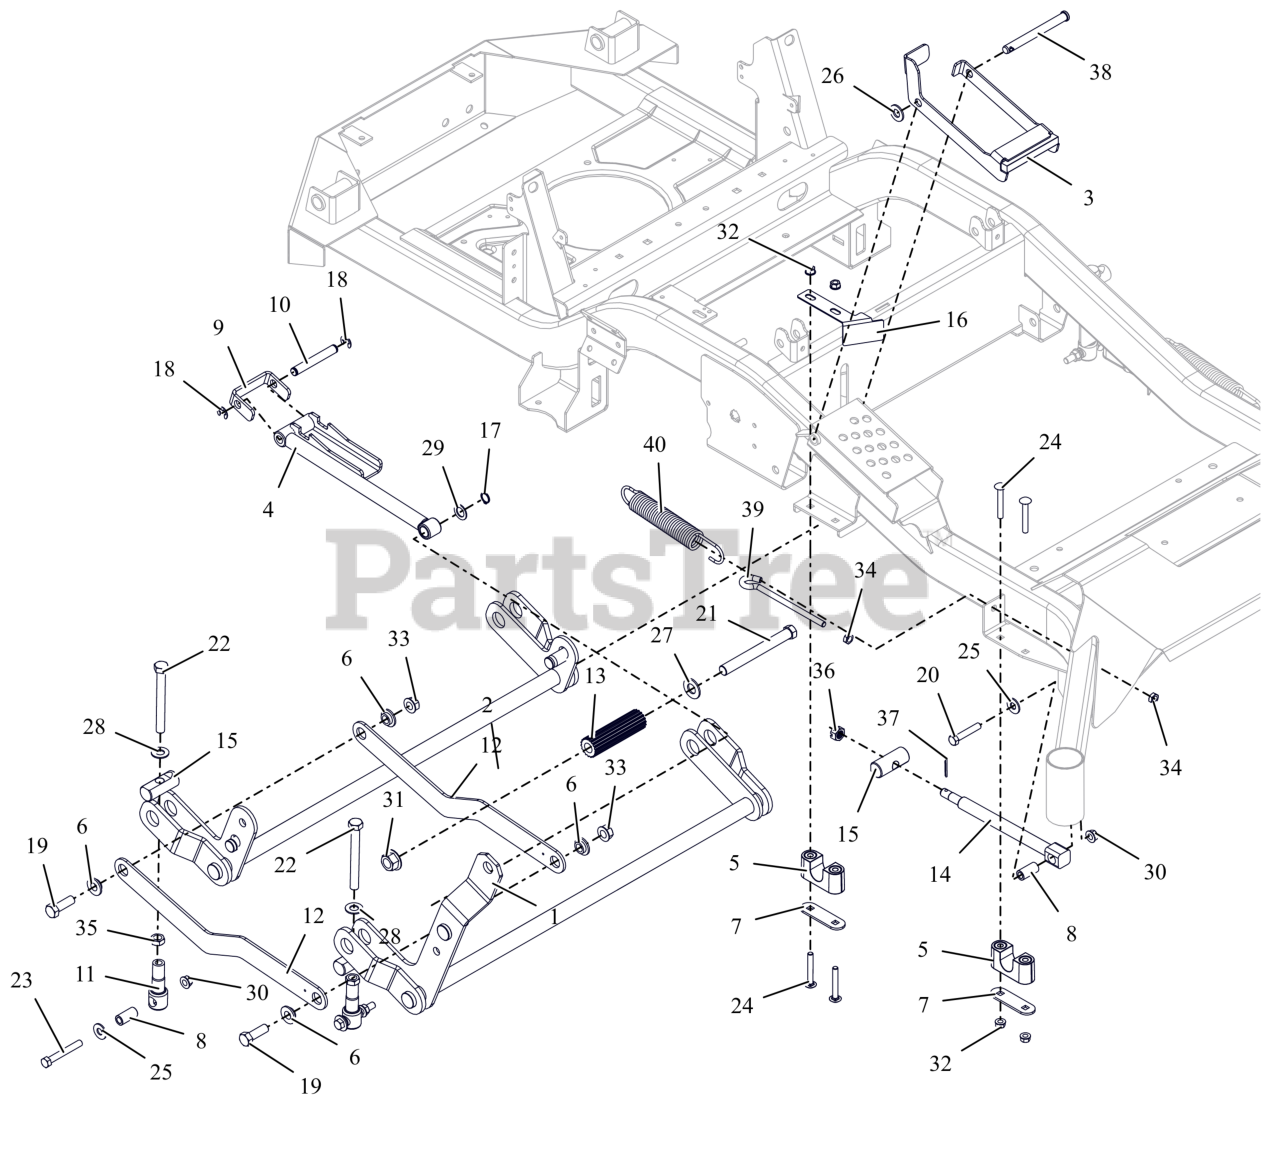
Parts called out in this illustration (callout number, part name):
1	WLDMT, FRONT DECK LIFT PIVOT
2	WLDMT, REAR DECK LIFT PIVOT
3	BRKT, HOC TRANSFER LOCK
4	WLDMT, HOC ARM
5	ASM-BUSHING, DECK LIFT
6	BSHG-FLG .515X.750X.395X1.120
7	PLATE, BEARING SUPPORT
8	SPACER, DECK LEVELING
9	BRKT, HOC LINE
10	ROD, HOC PIVOT
11	LINK, DECK LIFT FORMED
12	LINK, DECK LIFT
13	ROD, FOOT PEDAL (BLACK)
14	DRAG,LINK-HD
15	PIN, DECK LIFT
16	GUARD, STOP CE 60 (BLACK)
17	RG-RTNG-EXT .625X.050
18	RG-RTNG-EXT .500X.042 (E)
19	BLT,HEX .50-13X1.50 G5 ZCC
20	BLT,HEX .38-16X2.00 G5 ZCC
21	BLT, HEX .62-11X5.50 G5 FBP
22	BLT, HEX .50-13X4.50F G8 ZCC
23	BLT, HEX .38-16X2.75 G8 ZCC
24	BLT, RHSSN.31-18X2.25 G5 ZCC
25	WSHR,FLT .438X1.00X.083 ZCC
26	WSHR,FLT .531X1.062X.095 ZCC
27	WSHRFLT 5/8SAE CARBHARD FBP
28	WSHR, FLT .557X1.040X.102 ZCC
29	WSHR, FLT .630X1.005X.062 ZCC
30	NUT-LK-TOP-FLG .38-16 ZC120
31	NUT,FLG-TOP LK .625-11 FBP
32	NUT,LK-CTR-FLG .31-18 GF ZCC
33	NUT-LK-TOP-FLG .500-13 GF ZCC
34	NUT-JAM .375-16 G2 ZCC
35	NUT-JAM .500-13 G2 ZCC
36	NUT-SL .50-13
37	PIN,CTR.12X1.25EXTPRSQCT ZC120
38	PIN-SLIC .50X4.97X4.55 -ZCC
39	BOLT,.38-16 X 5.25-.62 DIA EYE
40	SG-TENS .162X1.25X8.25 WLD 25
